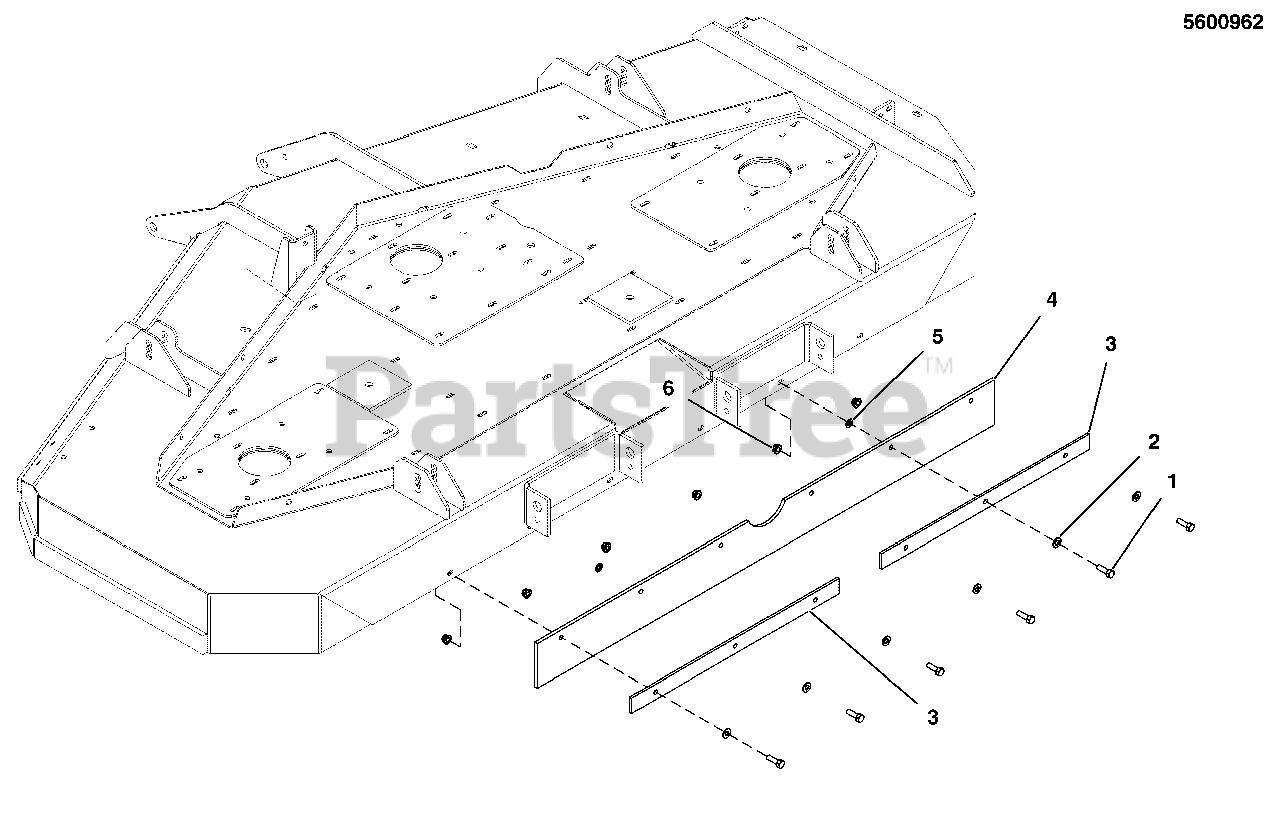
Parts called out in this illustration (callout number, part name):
1	CAPSCREW, Hex Head, 5/16-18 X 1
2	WASHER, Flat, 5/16
3	PLATE, SUPPORT - BLK
4	FLAP, STRIPER, 72 DECK
5	NUT, Push On, 5/16
6	NUT, 5/16-18, Flange Nylock, GR F, Zinc/Clear
